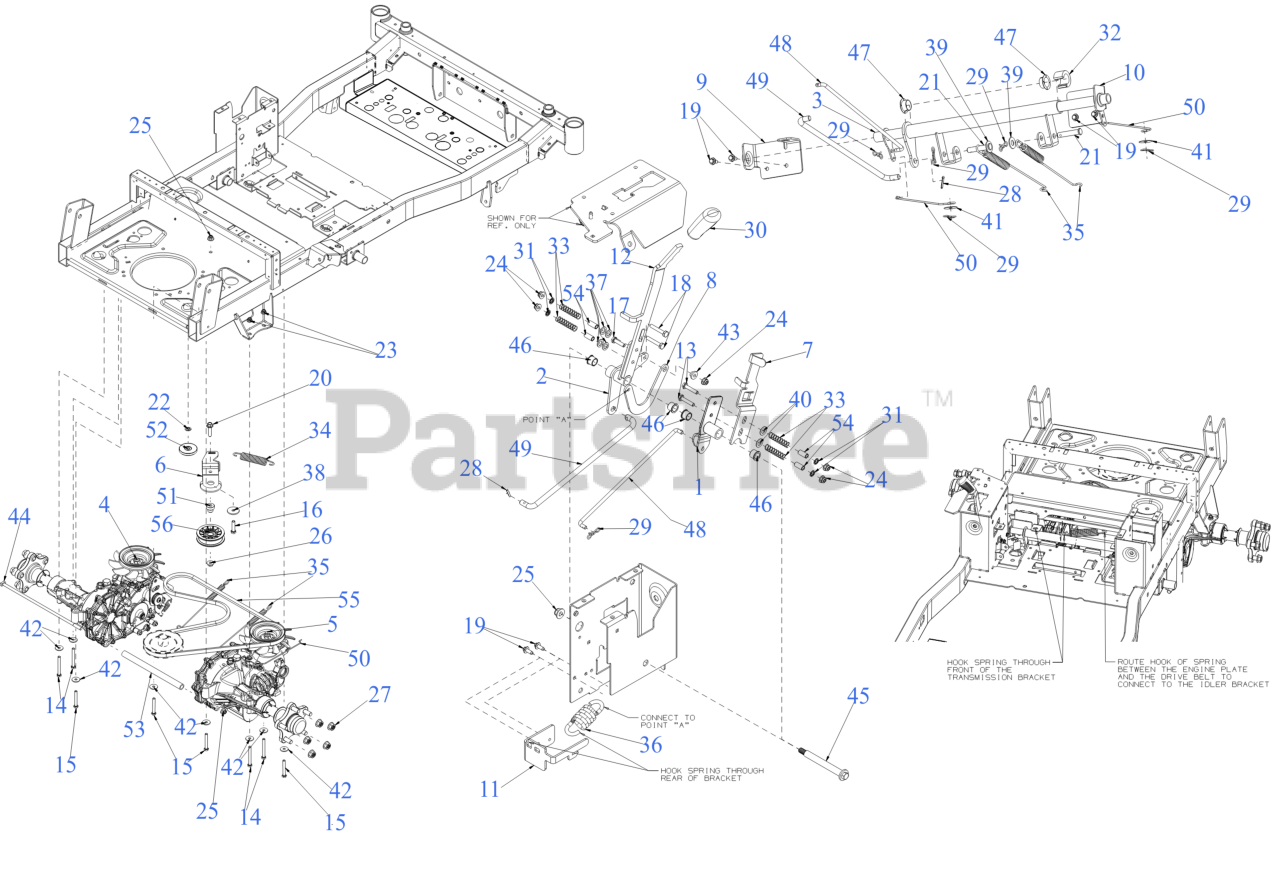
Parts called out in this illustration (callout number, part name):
1	BYPASS LEVER PIVOT ARM
2	PARK BRAKE PIVOT ARM
3	BRAKE PIVOT SHAFT
4	HYDRO TRANSMISSION (LH)
5	HYDRO TRANSMISSION (RH)
6	HYDRO DRIVE IDLER BRACKET
7	TRANSMISSION BYPASS LEVER
8	OVER CENTER LINK
9	BRAKE SHAFT SUPPORT (RH)
10	BRAKE SHAFT SUPPORT (LH)
11	SPRING MOUNTING BRACKET
12	PARK BRAKE LEVER
13	HEX SCREW 1/4-20 x 1.25
14	HEX SCREW 5/16-18 x 2.75
15	HEX SCREW 5/16-18 x 2.25 GR5
16	SCREW 3/8-16 x 1.50
17	SCREW 1/4-20 X1.00 GR5
18	SCREW 1/4-20 x 1.50 GR.5
19	SCREW M6-1 x .625
20	HEX HEAD BOLT (3/8-16:1.50 GR8)
21	CLEVIS PIN 3/8 x 1.87
23	FLANGE LOCK NUT 5/16-18
24	FLANGE LOCK NUT
26	FLANGE LOCK NUT
27	HEX FLANGE NUT 1/2-20 GR8
28	COTTER PIN
29	BOW TIE COTTER PIN 1/4-5/16
31	RETAINER-BOLT .25ID x .50OD
32	SPACER: .76ID x .75
33	COMPRESSION SPRING
34	EXTENSION SPRING .925 x 5.37
35	EXTENSION SPRING .60 DIAx9.09
36	EXTENSION SPRING 1.09x3.25
37	FLAT WASHER
38	FLAT WASHER .390x1.500x.134
39	FLAT WASHER
40	WASHER THRUST .375X.70X.030
41	FLAT WASHER
42	FLAT WASHER 1.0 OD:.331 ID
43	SHOULDER SPACER
44	SUPPORT TUBE ROD
45	SHOULDER SCREW .491x3.937 3/8-16
46	FLANGE BUSHING
47	FLANGE BEARING .75 x 1.125 x .375
48	BYPASS LINK
49	BRAKE LINK
50	HYDRO BYPASS ROD .100 DIA
51	SHOULDER SPACER
52	SHOULDER SPACER
53	SUPPORT TUBE
54	SPACER .252x.350x.760
55	TRANSMISSION DRIVE BELT A x 67
55	Cub Cadet TRANS DRIVE BELT A x 67 RZT
55	Troy-Bilt TRANSMISSION DRIVE BELT
56	FLAT IDLER PULLEY 3.00 OD
